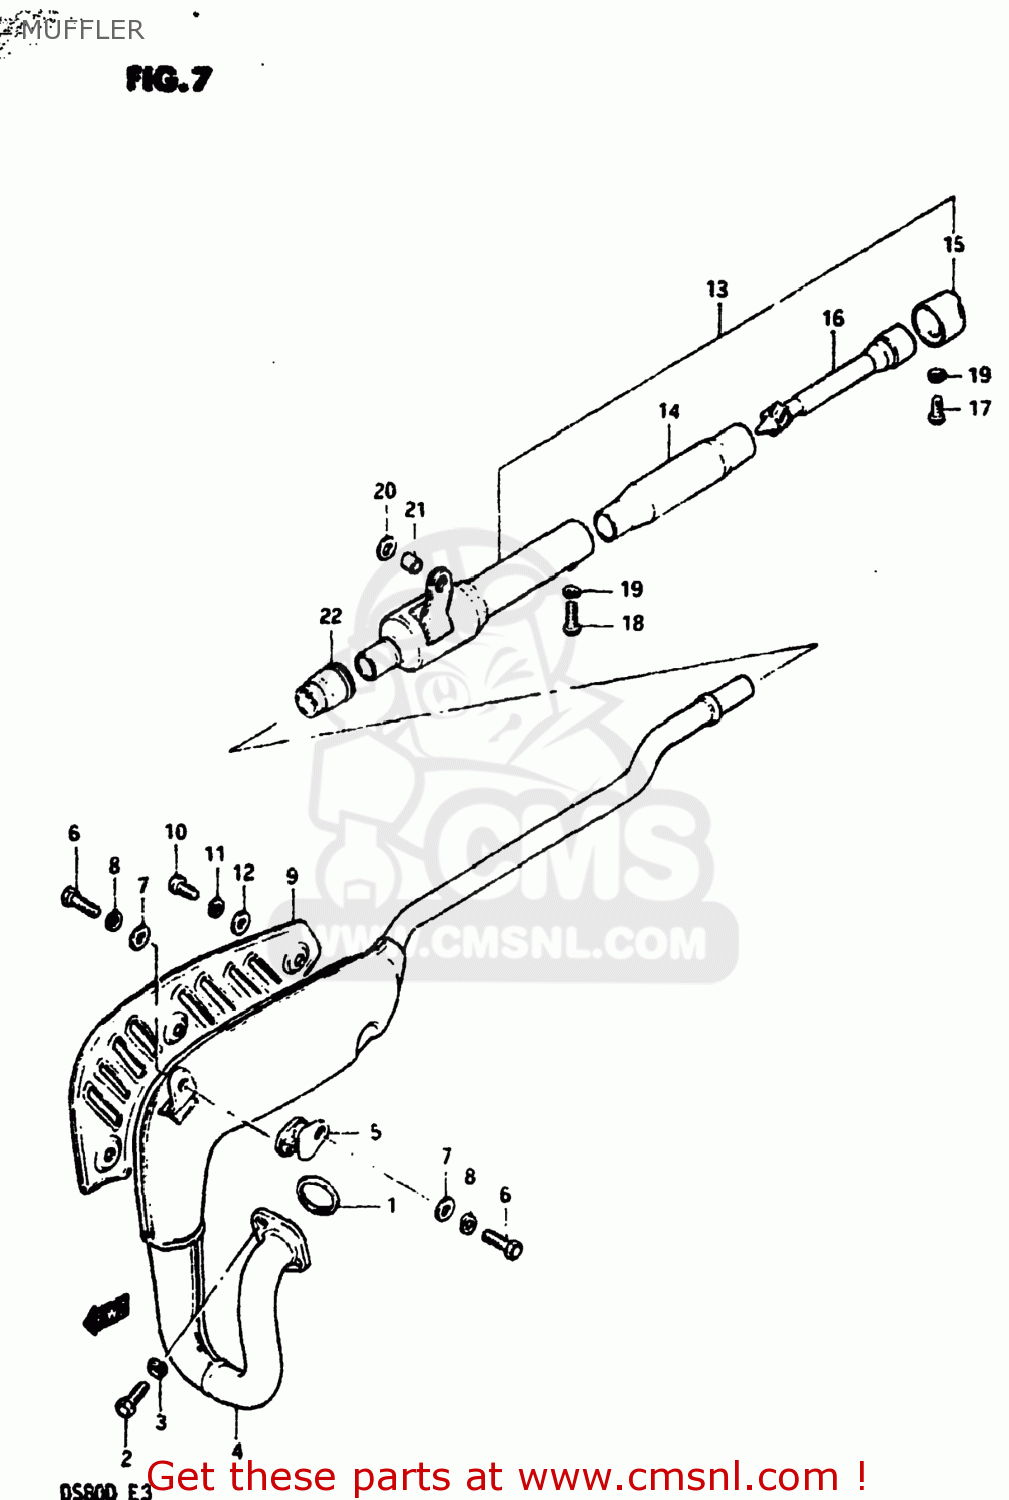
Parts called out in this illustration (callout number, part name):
1	GASKET,EXHAUST PIPE (NAS)
2	BOLT
3	LOCK WASHER
4	BODY,MUFFLER
5	DAMPER,MUFFLER SUPPORT
6	BOLT
7	WASHER
8	LOCK WASHER
9	COVER,MUFFLER
10	SCREW
11	LOCK WASHER
12	WASHER
13	MUFFLER ASSEMBLY
14	SHELL,ARRESTER
15	CUTTER,MUFFLER TAIL
16	TUBE,CLEAN OUT
17	SCREW
18	SCREW
19	LOCK WASHER
20	WASHER
21	SPACER (8.6X13.8X9)
22	CONNECTOR,MUFFLER
